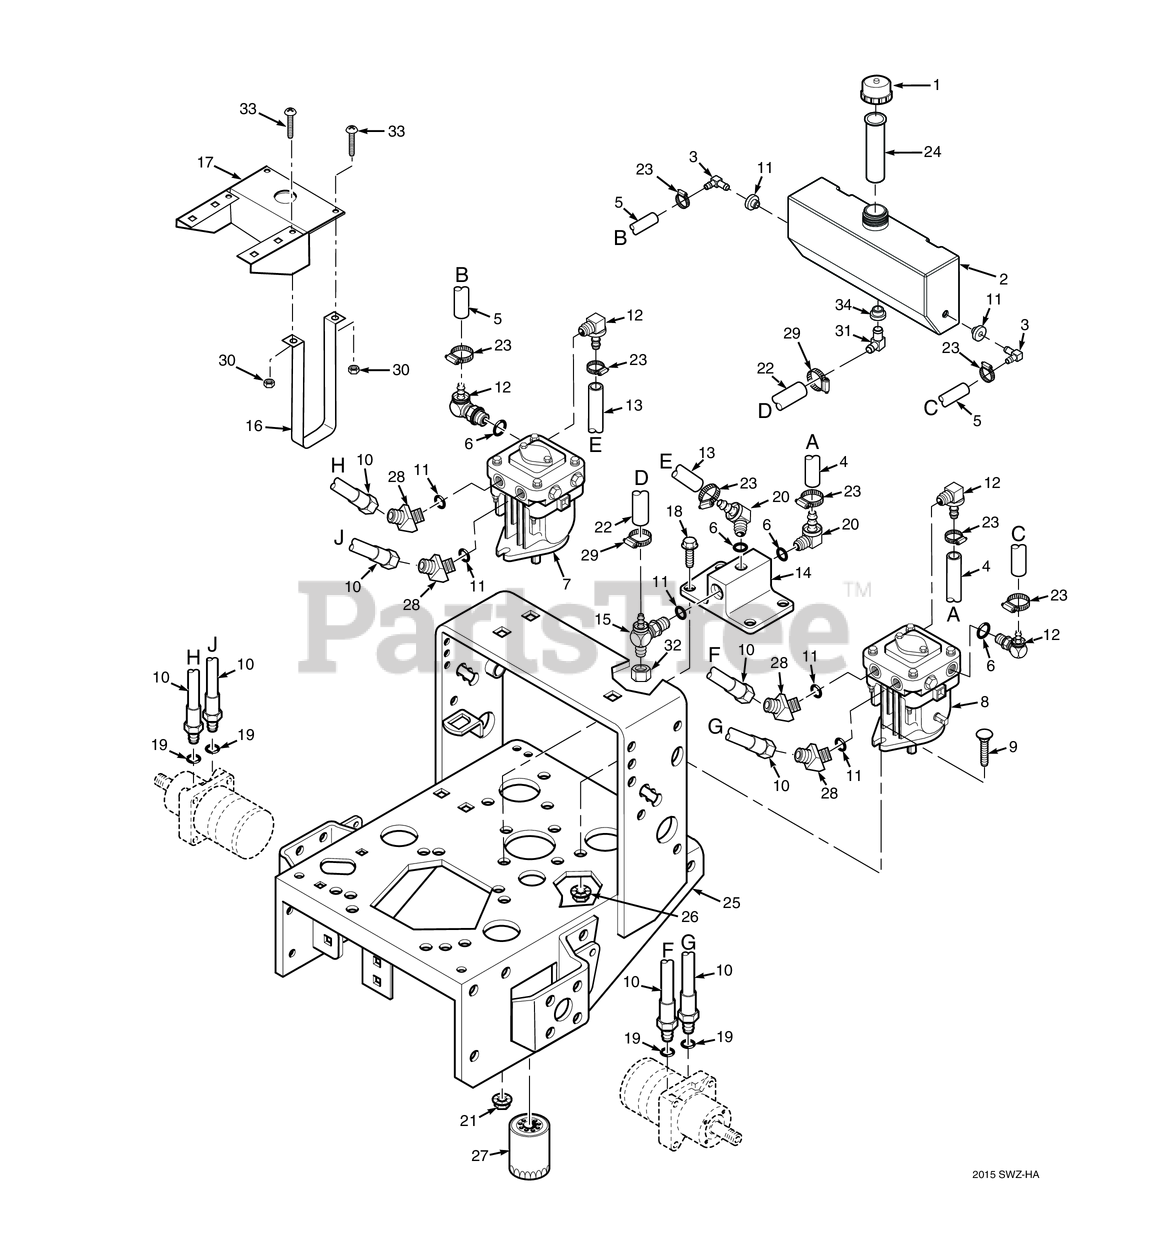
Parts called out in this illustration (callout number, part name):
1	CAP, HYDRAULIC TANK
2	Oil Reservoir (With Fittings)
3	Elbow, 90 Degree, 9/16-18 JIC x 9/16 O-Ring
4	Hose, 3/8" ID - 10-1/4" Long (Order By The Inch)
5	Hose, 3/8" ID - 10-1/4" Long (Order By The Inch)
6	"O" RING, 5/64 X 15/32 ID
7	Pump, PG-1JQQ-DY1X-XXXX (R.H.)
8	Pump, PG-1GQQ-DY1X-XXXX (L.H.)
9	SHORT SQ. NECK CARRIAGE BOLT, 3/8-16 X 1-1/4"
10	Hose, Pump to Wheel Motor
11	Bushing, 0.56" Dia. Viton
12	Elbow, 90 deg. 7/16-20 JIC to 9/16-18 "O" Ring
13	Hose, 3/8" ID - 10-1/4" Long (Order By The Inch)
14	Filter Head Assembly
15	Tee, 3/8" O-Ring x JIC x 1/2" Hose
16	Strap, Hydraulic Tank
17	Bracket, Hydraulic Tank
18	Capscrew, 5/16-18 x .75 Serrated Flange Hex Head
19	"O" RING, 3/32 X 3/4 ID
20	Elbow, 90 Degree - 9/16" O-Ring x 3/8" Hose
21	Nut, Serrated Flange 5/16-18 (Right Front Engine Mounting, Briggs and Kohler Only)
22	Hose, Formed 1/2" ID
23	Clamp, .69" Max. / .25" Min. Dia.
24	Insert, Filler Neck
25	Engine Deck (16" Wide) with Decals - Small Frame
25	Engine Deck (20" Wide) with Decals - Large Frame
26	NUT, 3/8-16 SERRATED FLANGE HEX HEAD
27	OIL FILTER, SPECIAL
28	Elbow, 45 Deg. - 3/4-16 JIC Male x Male 3/4-16 O-Ring
29	Clamp, Cable 3/4" I.D.
30	HEX, NUT, ELASTIC STOP LOCK, 1/4-20
31	Fitting, 90 Degree - 1/2" Hose
32	CAP, 3-4-16 JIC
33	Machine Screw, Round Head, 1/4-20 x 2.00"
34	Bushing, 0.78" Dia. Viton
